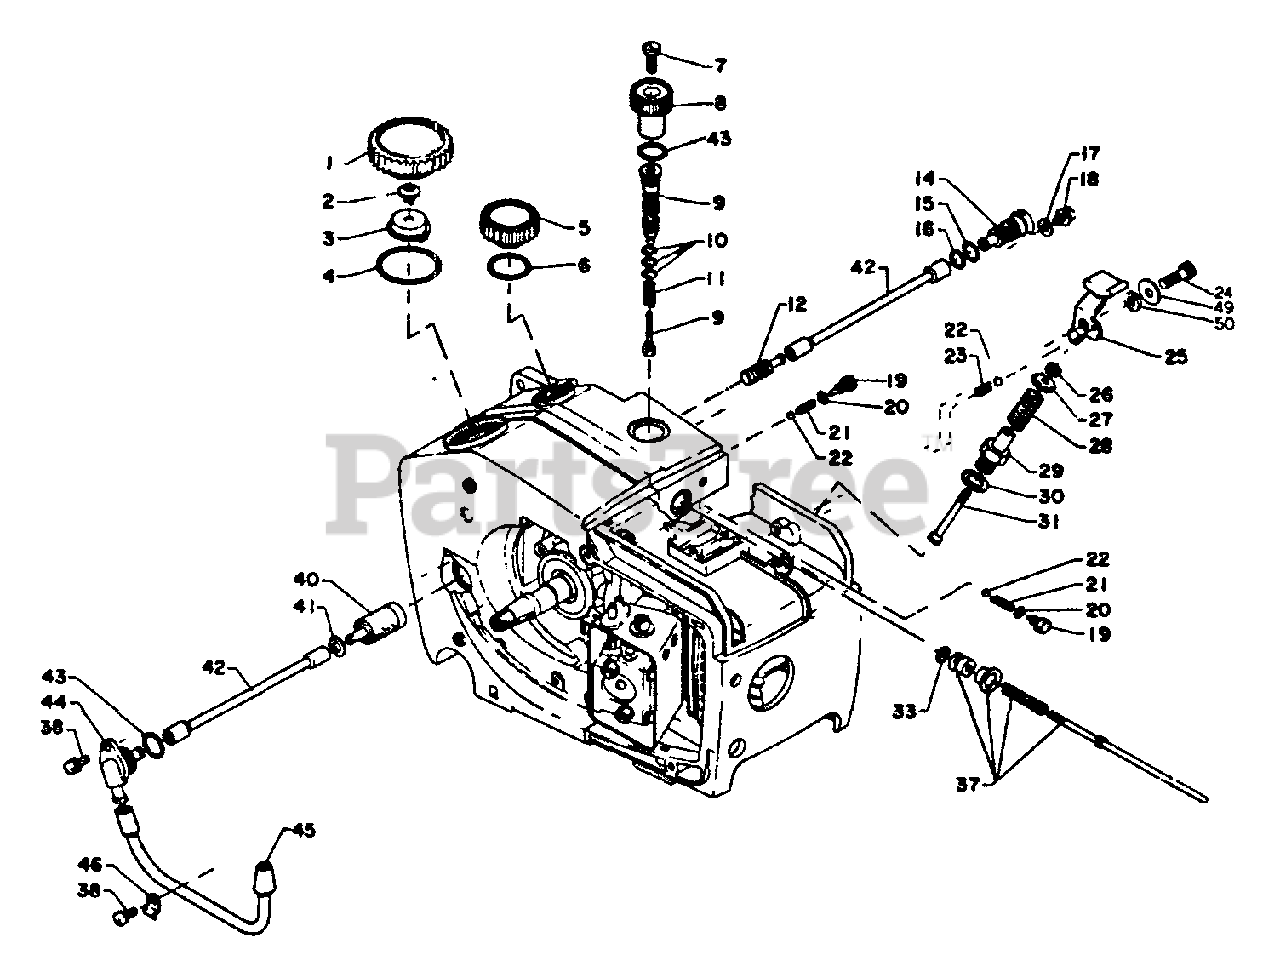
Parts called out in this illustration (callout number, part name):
1	CAP
3	HOLDER, VENT
4	O-RING - 29
5	CAP ASSY
6	O-RING - 16
7	SCREW
8	DIAL, AUTO-OILER
9	PUMP KIT
10	O-RING - 5
12	FILTER, OIL
14	CONNECTOR, PIPE
15	O-RING - 9
16	O-RING - 8
17	WASHER
18	SCREW - 4X10
19	ADAPTER, OIL PUMP
21	SPRING, VALVE
22	BALL
24	SCREW - 5X15
25	LEVER, DECOMPRESSION
28	SPRING, VALVE
29	SEAT, VALVE
30	SEAL
31	VALVE, DECOMPRESSION
33	O-RING - 6
37	PUMP ROD ASSY
38	SCREW - 4X10
40	FILTER, FUEL
41	WASHER - 5
42	PIPE - INNER
43	O-RING - 12
44	CONNECTOR, PIPE
45	PIPE, FUEL - OUTER
49	WASHER - 5
